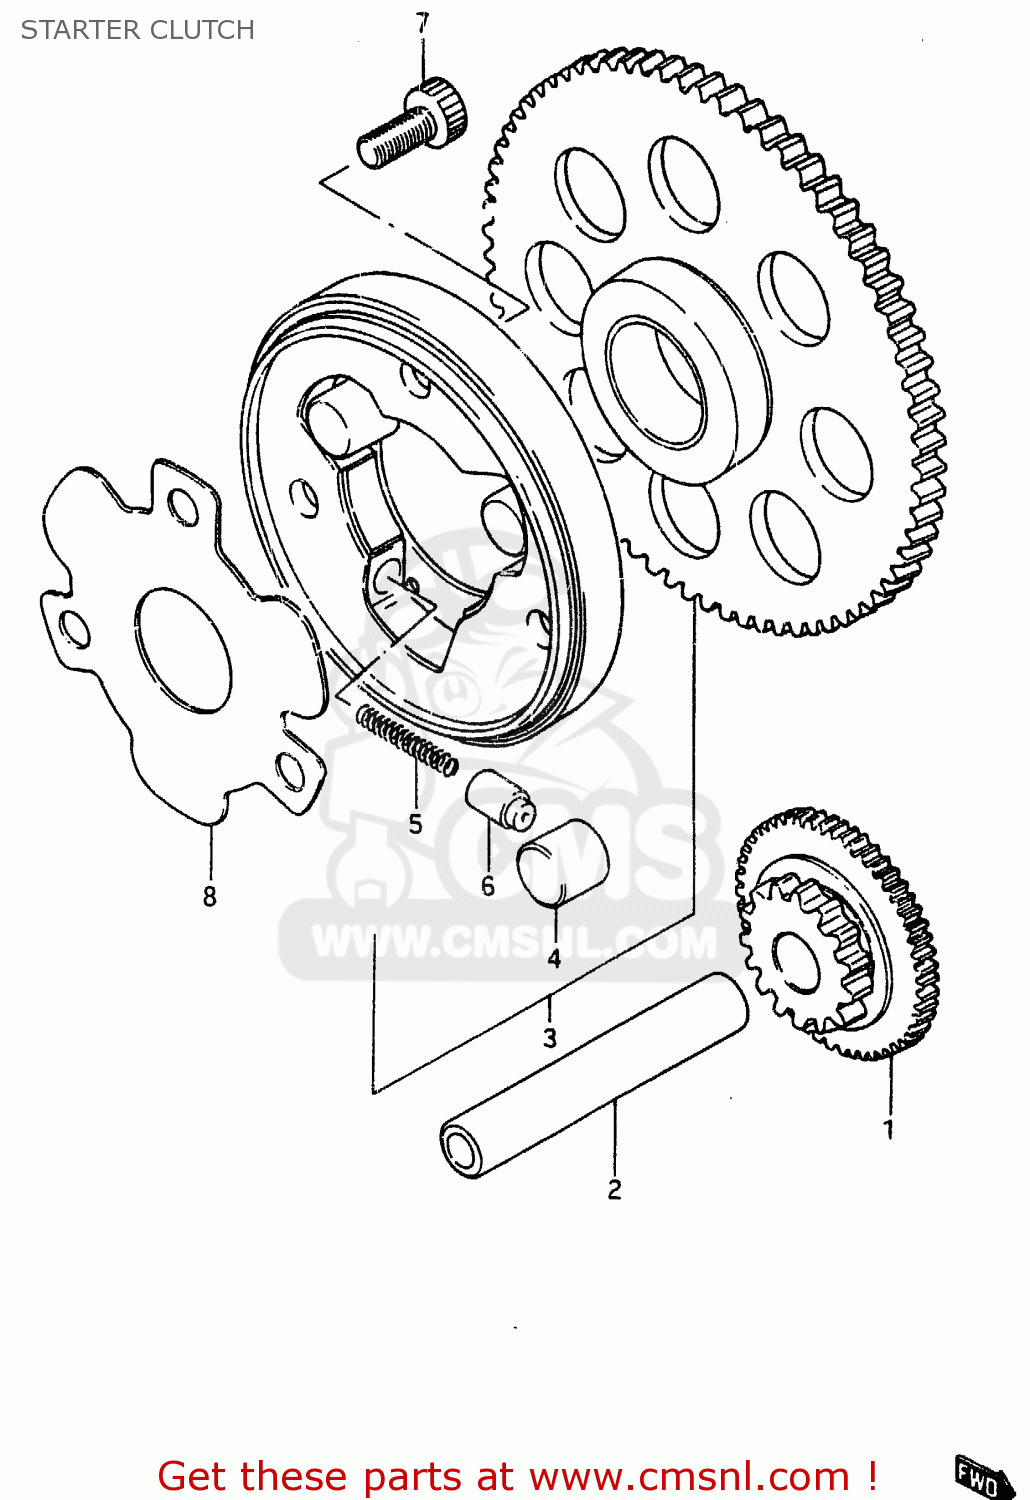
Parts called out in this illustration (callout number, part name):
1	GEAR,STARTER IDLE
2	PIN(7.4X13X56)
3	CLUTCH SET,STARTER
4	PIN(14X13)
5	SPRING
6	PIECE,PUSH
7	BOLT
8	SHIM,STARTER CLUTCH HUB
